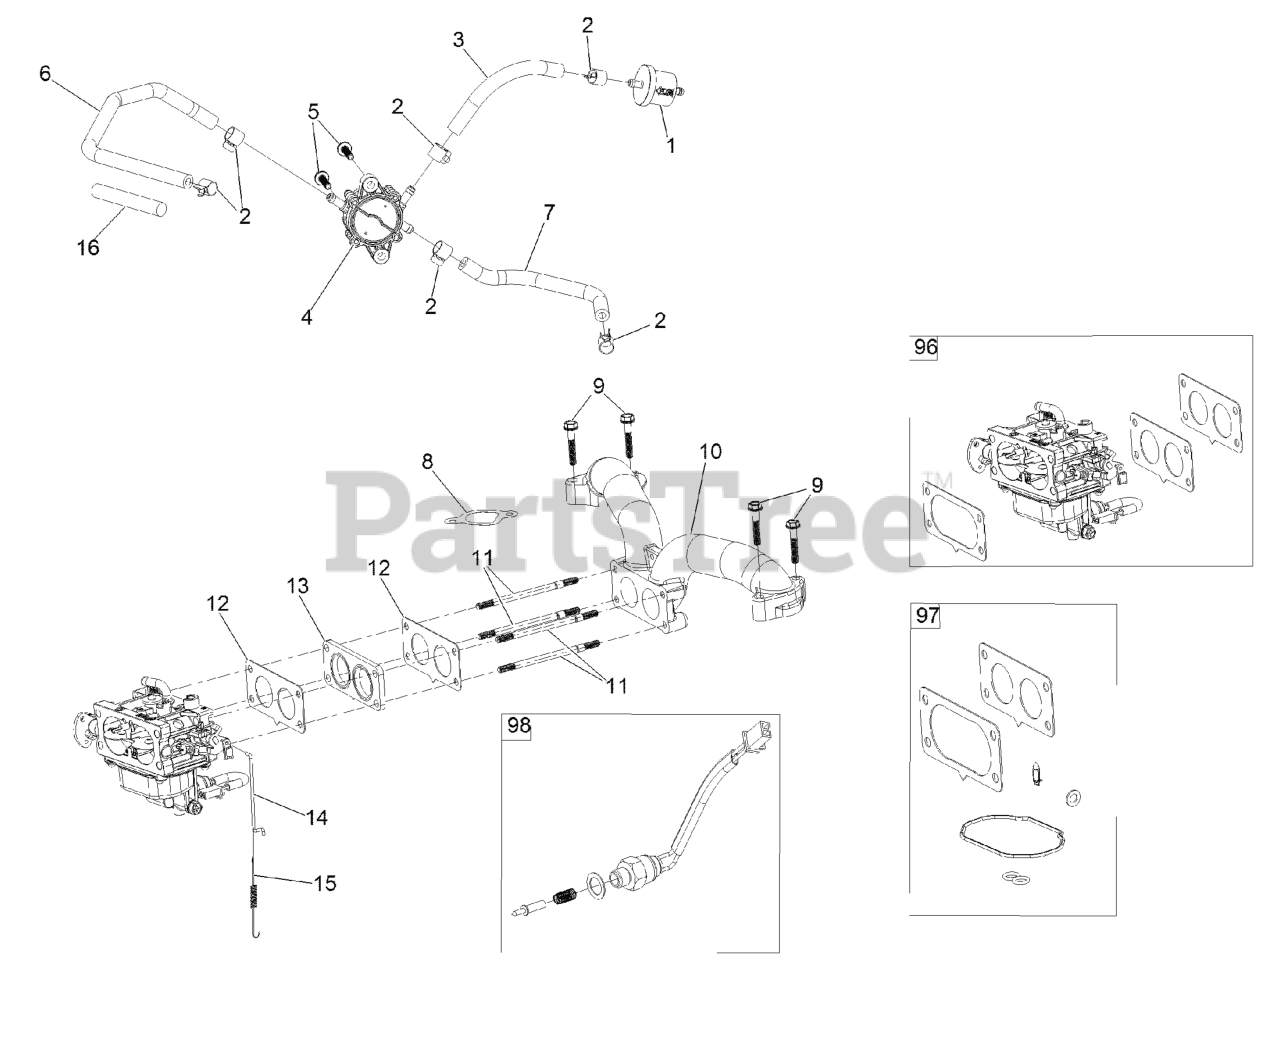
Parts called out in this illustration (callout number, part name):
1	FILTER-FUEL
2	CLAMP-FUEL LINE
3	LINE-FUEL
4	PUMP-FUEL
5	SCREW-HHF
6	HOSE-FUEL
7	HOSE-FUEL
8	GASKET-INTAKE
9	SCREW-HHF
10	MANIFOLD-INTAKE
12	GASKET-CARBURETOR
13	INSULATOR-CARBURETOR
14	LINKAGE-THROTTLE
15	SPRING-RETURN, THROTTLE
16	SLEEVE-FUEL LINE PROTECTO
96	CARBURETOR REPLACEMENT KI
97	CARBURETOR REPAIR KIT
98	SOLENOID KIT
